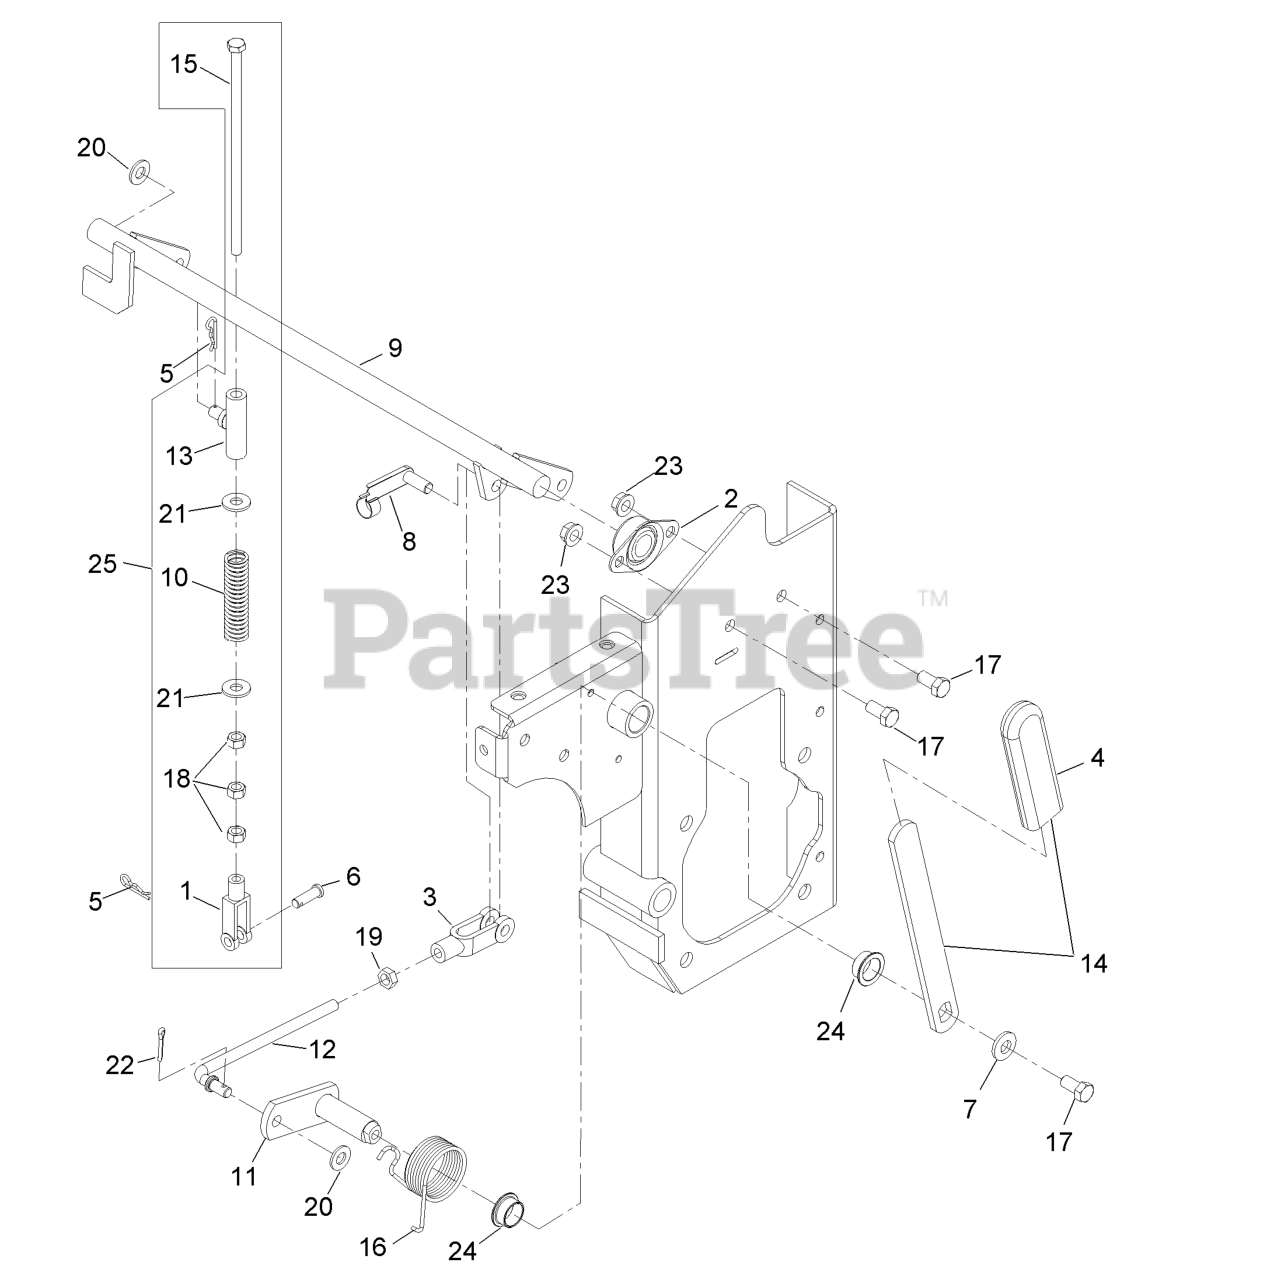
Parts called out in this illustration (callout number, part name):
1	YOKE-ADJUSTABLE
2	BEARING-FLANGE, SIDE
3	YOKE-LINKAGE, BRAKE
4	GRIP-LEVER
5	PIN-COTTER
6	PIN-CLEVIS
7	WASHER-BELLEVILLE
8	PIN-SPRING, CLEVIS
9	WLD, BRAKESHAFT
10	SPRING,COMPRESSION
11	WLD,BRAKE PIVOT (PLATED)
12	ROD,LINKAGE BRAKE (PLATED
13	WLD,SWIVEL BRAKE (PLATED)
14	PARK BRAKE HANDLE ASM
15	SCREW-HH
16	SPRING,TORSION RH
17	SCREW-HH
18	NUT-HEX
19	NUT-HEX
20	WASHER-FLAT
21	WASHER-FLAT
22	PIN-COTTER
23	NUT-HHF, WHIZ
24	BUSHING-BRONZE
25	ASM,BRAKE LINKAGE
